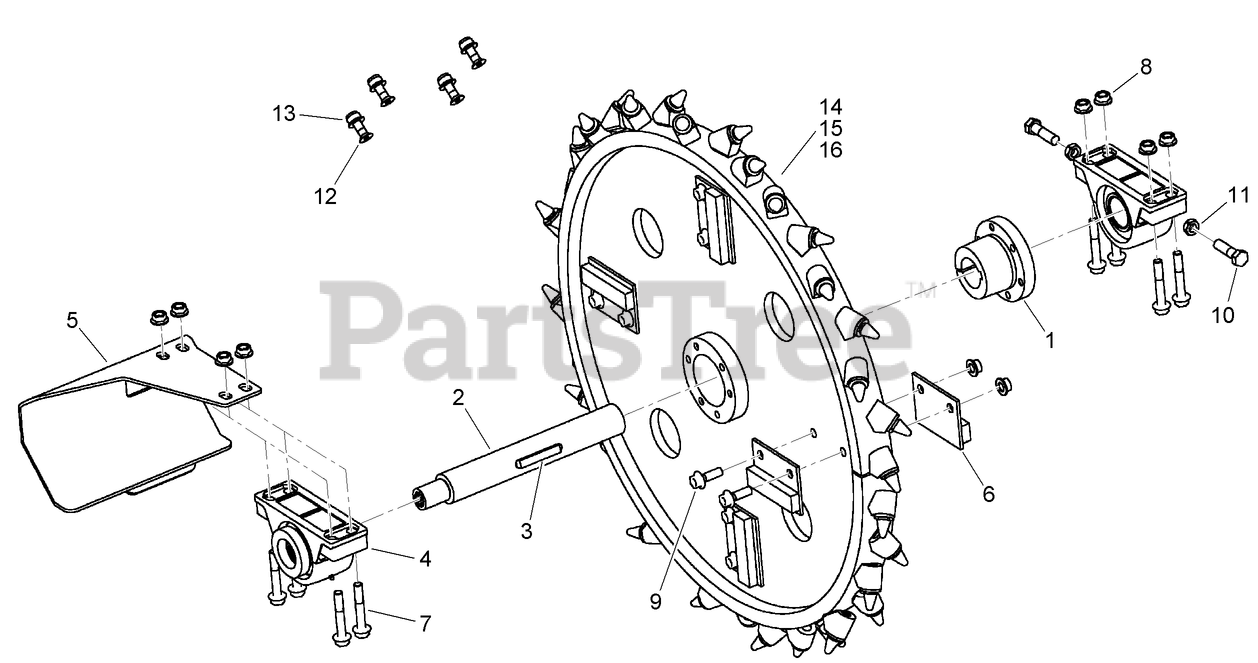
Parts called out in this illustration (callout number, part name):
1	BUSHING - QD
2	WELDMENT - Center Shaft
3	KEY - Center Shaft
4	BEARING - SKF
5	PLATE - Motor Guard
6	WELDMENT - Breaker
7	SCREW, METRIC FLANGE w/BODY - M16 x 100
8	NUT, METRIC FLANGE PREVAILING - M16 Zinc
9	SCREW-FLANGE
10	BOLT - Hex Hd 0.75 x 2.75 GR8 ZND
11	NUT - Hex Jam 0.75 - 10 GR5 ZND
12	SCREW-HSFH
13	NUT-HHF
14	ASSEMBLY - Cutting Wheel, 17in x 3in
15	ASSEMBLY - Cutting Wheel, 18in x 4in
16	ASSEMBLY - Cutting Wheel, 18in x 6in
